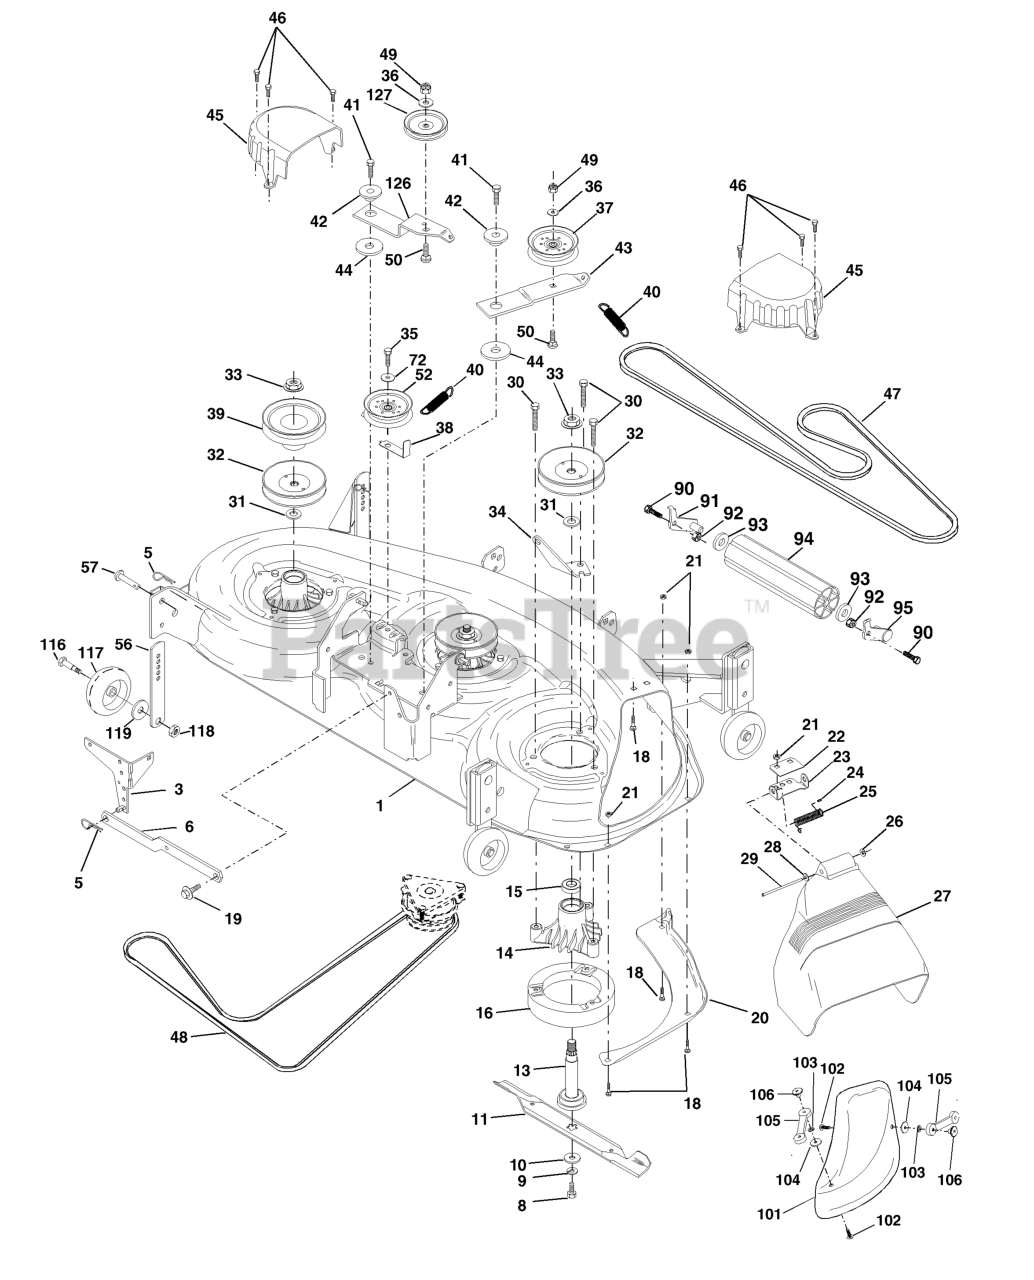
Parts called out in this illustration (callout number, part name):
1	DECK SVC W/ADJ.GWB.46"
3	BRACKET SWAY BAR
5	RETAINER-SPRNG RB
6	REAR SUSP ARM
8	BLADE BOLT
9	LOCKWASHER
10	WASHER.BLADE
11	BLADE.46".HI-LIFT.PREMIUM
11	MULCH BLADE 46"
13	SHAFT.ASM.W/BEARING
14	HOUSING.MANDREL.44/46" VENT
16	STRIPPER
18	BOLT
19	BOLT SHD 5/16-18
20	BAFFLE, VORTEX MOWER 46"
21	LOCKNUT
22	BRKT, STIFF 42" DECK
23	BRKT, DEFLECTOR MOWER 42"
24	CAP-SLEEVE LT
25	TORSION SPRING
26	NUT PUSH M
27	SHIELD DEFLECTOR
28	Washer 11/32 x 5/8 x 16 Ga.
29	ROD.HINGE
30	SCREW THDROL ROLLING WASHER HD
31	WASHER
32	MANDREL PULLEY
33	NUT
34	ANCHOR SPRING, DECK 46"
35	SCREW LT
36	WASHER
37	PULLEY.IDLER.FLAT
38	REPL BY 532 1560-86
39	REPL BY 532 1449-17
40	SPRING.SEC.44"VEN
41	SCREW.3/8-16
42	SPACER RETAINER
43	ARM, IDLER, SECONDARY
44	HARDENED WASHER
45	COVER MANDREL 46
46	SCREW.1/4-20X5/8
47	BELT V SECONDARY
48	V-BELT PRIMARY 50"
50	BOLT.3/8-16X1.50
52	PULLEY.IDLER.FLAT.46".PRIMARY
56	BAR.ADJUST.WHEEL.ANTI.SCALP.BL
57	RIVET.PIN.HEAD.YELLOW.
72	WASHER
90	BOLT
91	BRACKET LH (A)
92	NUT
93	Washer 17/32 x 7/8 x 16 Ga.
94	NOSE ROLLER
95	BRACKET RH (B)
101	COVER.MULCH.46"3-BLADE.(2 2)
102	SCREW
103	LOCKWASHER #10
105	LATCH ASSY
106	WELDNUT
116	BOLT, SHOULDER
117	WHEEL GAGE DONUT
118	LOCKNUT
119	WASHER.5/16.FLAT.STE.STD.
126	ARM, IDLER PRIMARY DECK
127	REPL BY 532 1467-63
